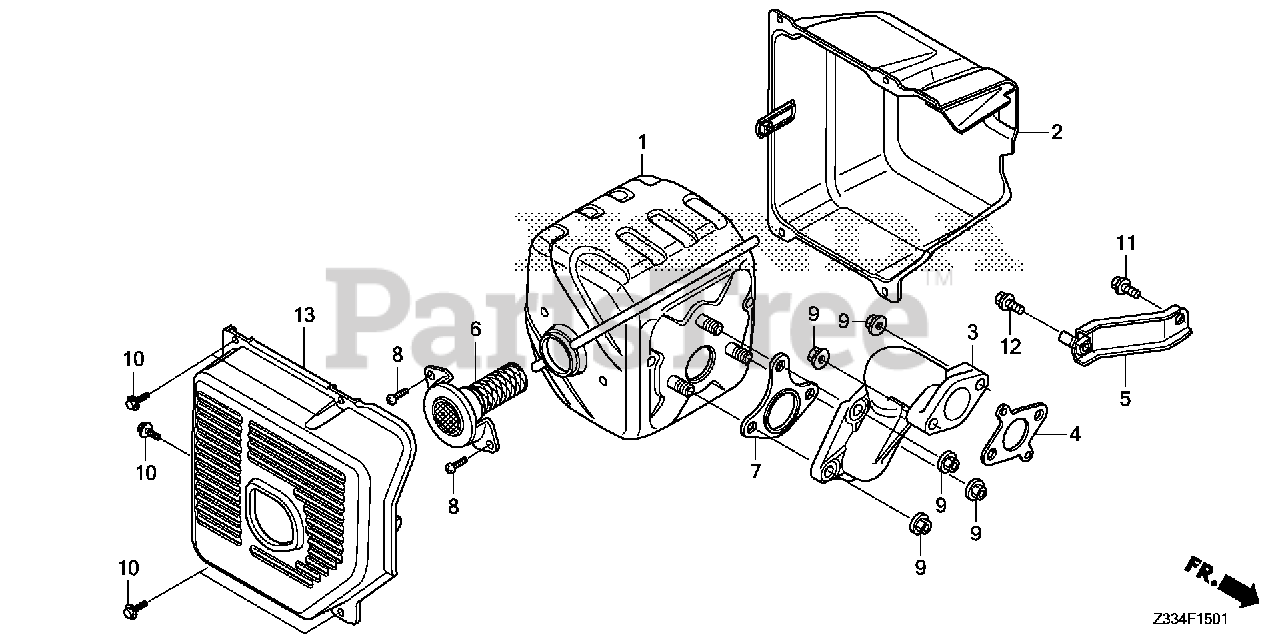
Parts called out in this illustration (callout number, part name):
2	PROTECTOR, MUFFLER (INNER) *NH105* (MAT BLACK)
4	GASKET, EX. PIPE
5	STAY, MUFFLER
6	ARRESTER, SPARK
7	GASKET, MUFFLER (NIPPON LEAKLESS)
8	SCREW, TAPPING (5X8)
9	NUT, FLANGE (8MM)
10	BOLT, FLANGE (6X10)
11	BOLT, FLANGE (8X16)
12	BOLT, FLANGE (8X22)
13	PROTECTOR, MUFFLER (OUTER) *NH105* (MAT BLACK)
